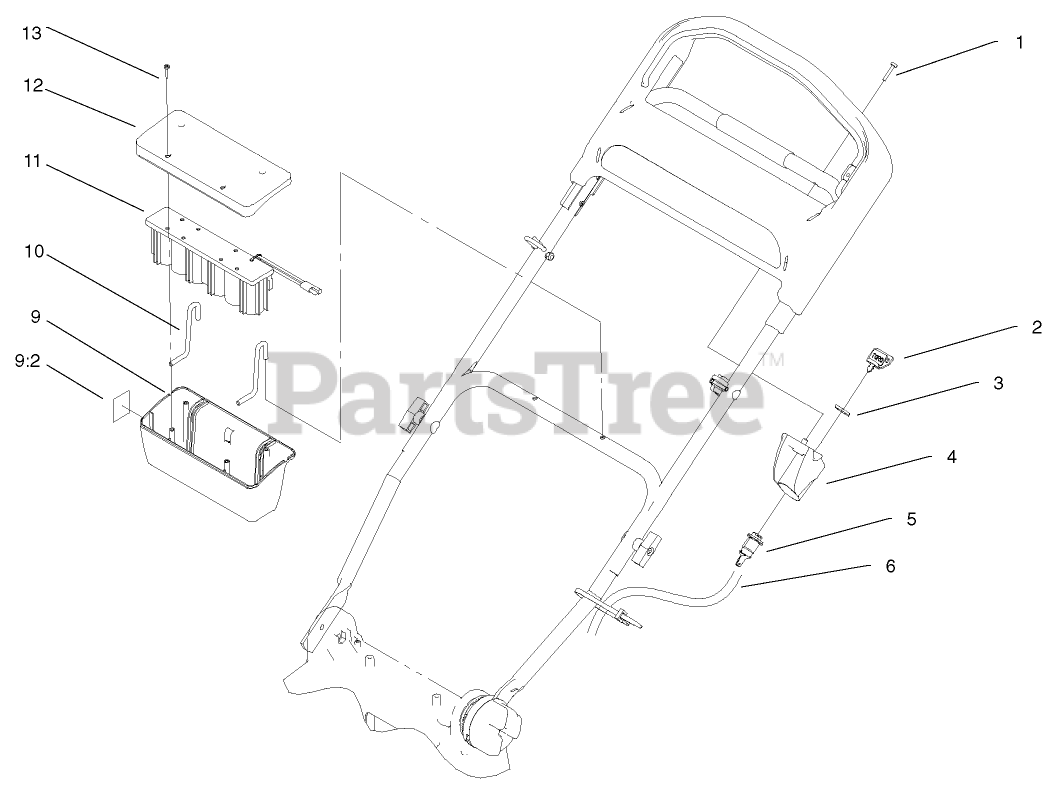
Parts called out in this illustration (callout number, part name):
1	SCREW-PPH, PLASTITE
2	KEY-IGNITION
3	NUT-HH
4	SWITCH-HOLDER
5	STARTER SWITCH ASM
6	WIRE-HARNESS
9	BOX ASM
9:2	DECAL-BOX, BATTERY
10	ROD-BATTERY
11	BATTERY-WET
12	COVER-BATTERY
13	SCREW-PPH
